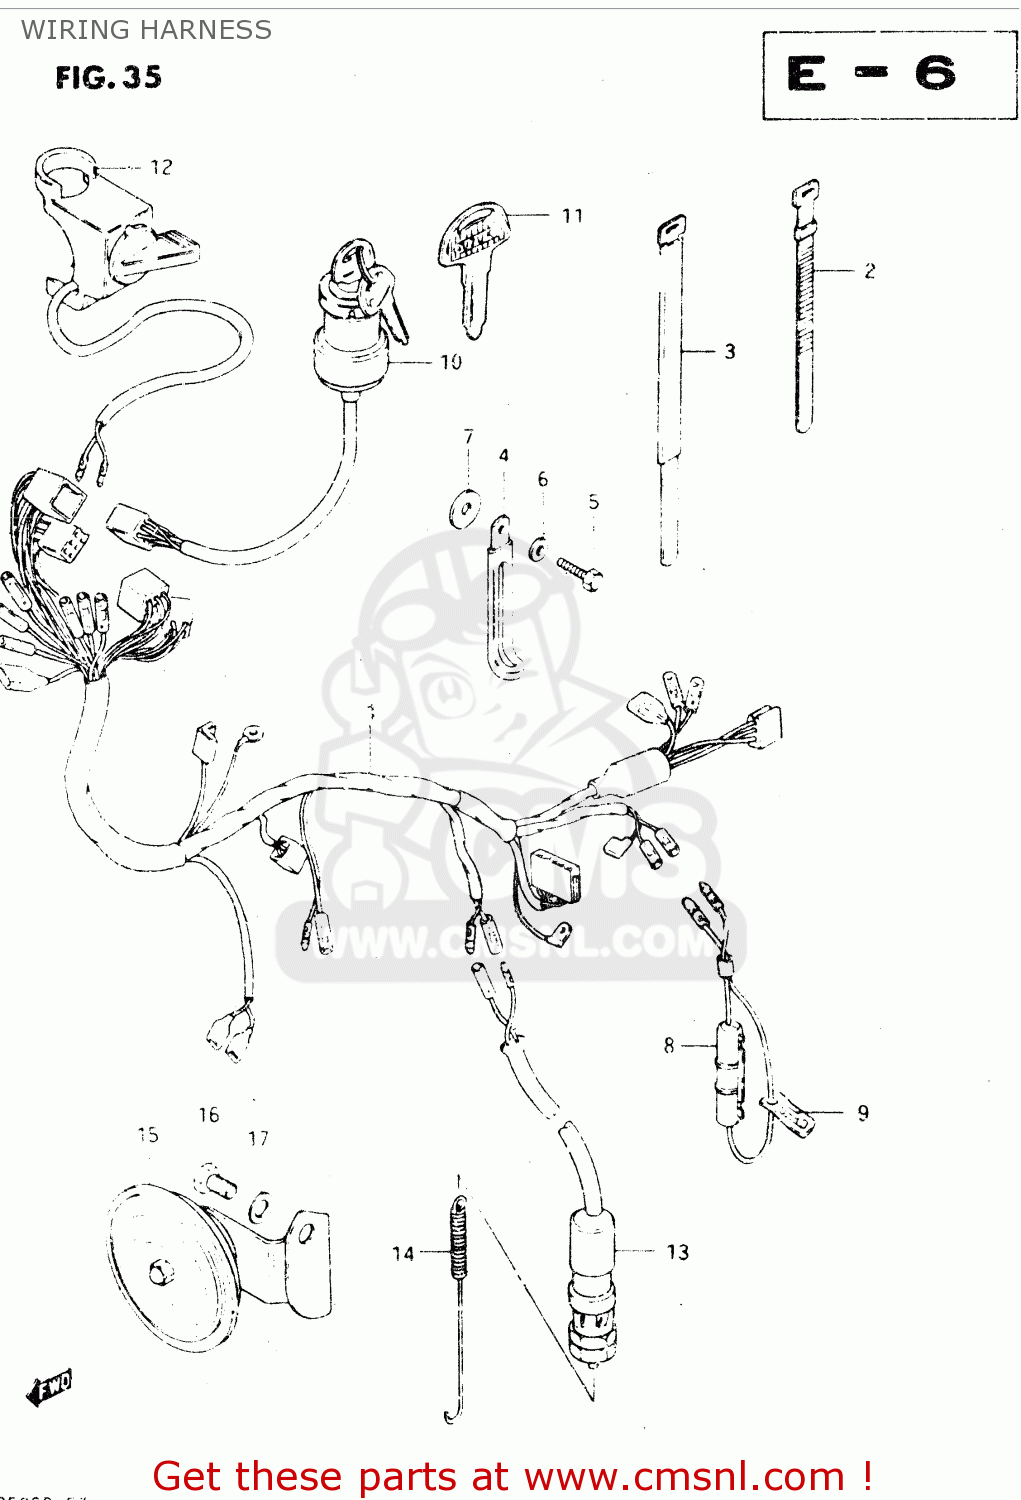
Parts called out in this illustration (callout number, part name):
1	HARNESS,WIRING
2	CLAMP(L:120)
3	CLAMP
4	CLAMP
5	BOLT, UPPER
6	WASHER
7	WASHER
8	BOX ASSEMBLY,FUSE
9	FUSE(15A)
10	SWITCH ASSEMBLY,IGNITION
11	KEY,BLANK
12	SWITCH ASSY,ENGINE STOP
13	SWITCH ASSEMBLY,STOP LAMP
14	SPRING
15	HORN ASSY
16	BOLT
17	WASHER
